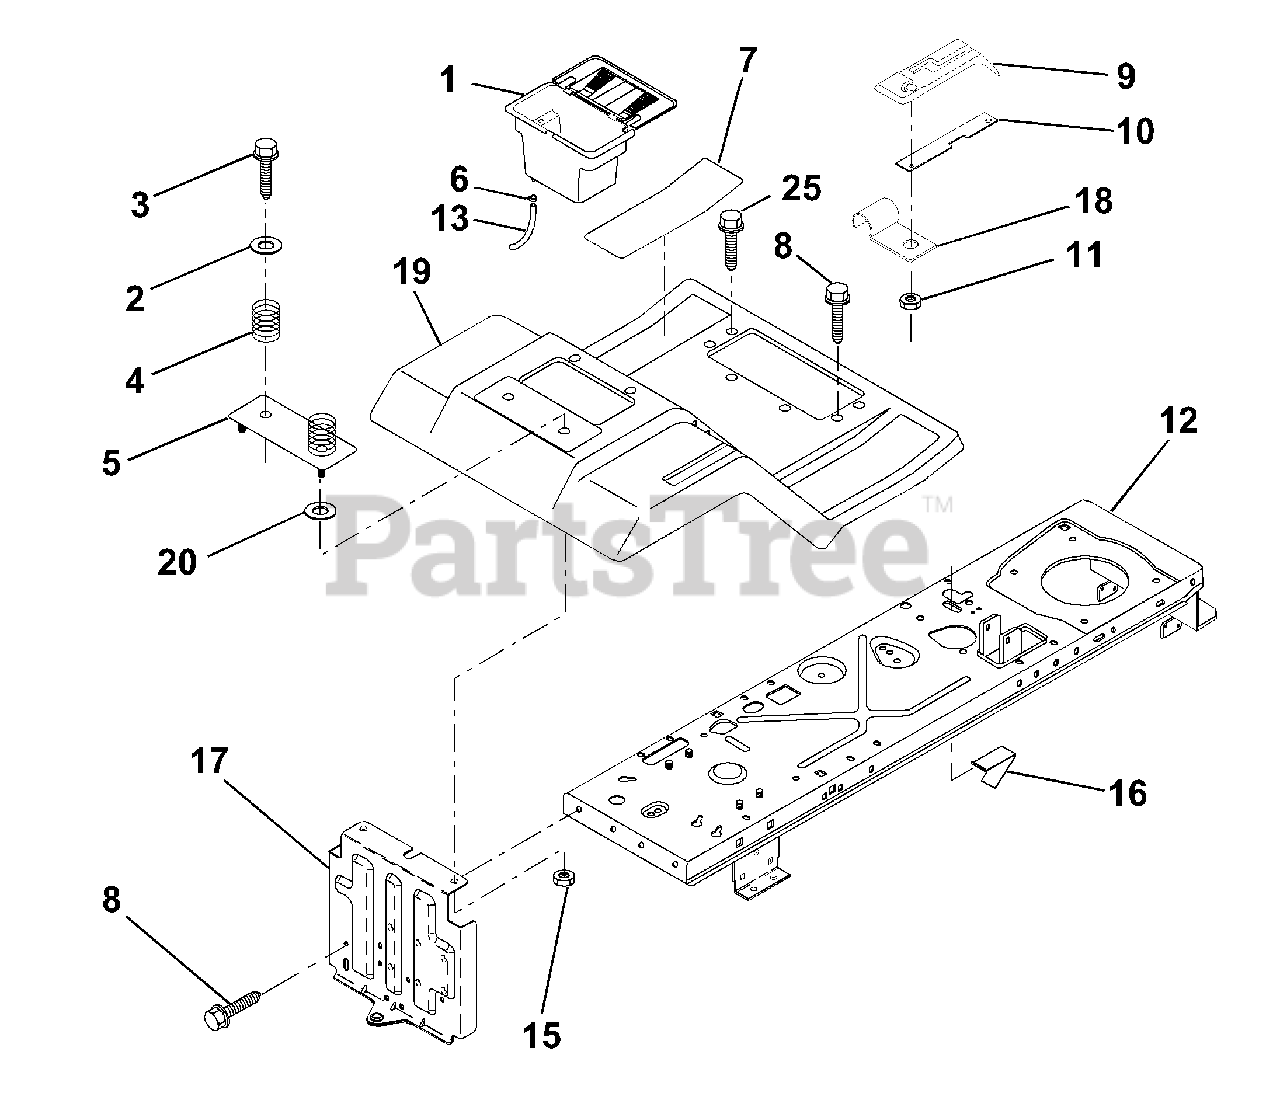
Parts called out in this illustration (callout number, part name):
1	Case, Battery
2	Washer 13/32 x 1-1/4 x 12 Ga.
3	Screw, Hex Wsh. Thrdrol 3/8-16 x 3/4
4	Spring, Compression, Seat
5	Plate, Asm. Battery
6	Clamp, Hose
7	Pad, Footrest
8	Screw Thdrol 5/16-18 x 3/4
9	Console, Shift Control
10	Bar, Shift Lock
11	Nut, Self-Threading, Wsher Hd 3/16
12	Assembly, Frame
13	Tube, Battery Drain
15	Nut, Keps 1/4-20 UNC
16	Switch Actuator
18	Clip, Insulated
19	Fender/Footrest
20	Washer 9/32 x 7/8 x 13 Ga.
25	Scr-Hx Wsh Thd Rol 5/16-18 x 1
